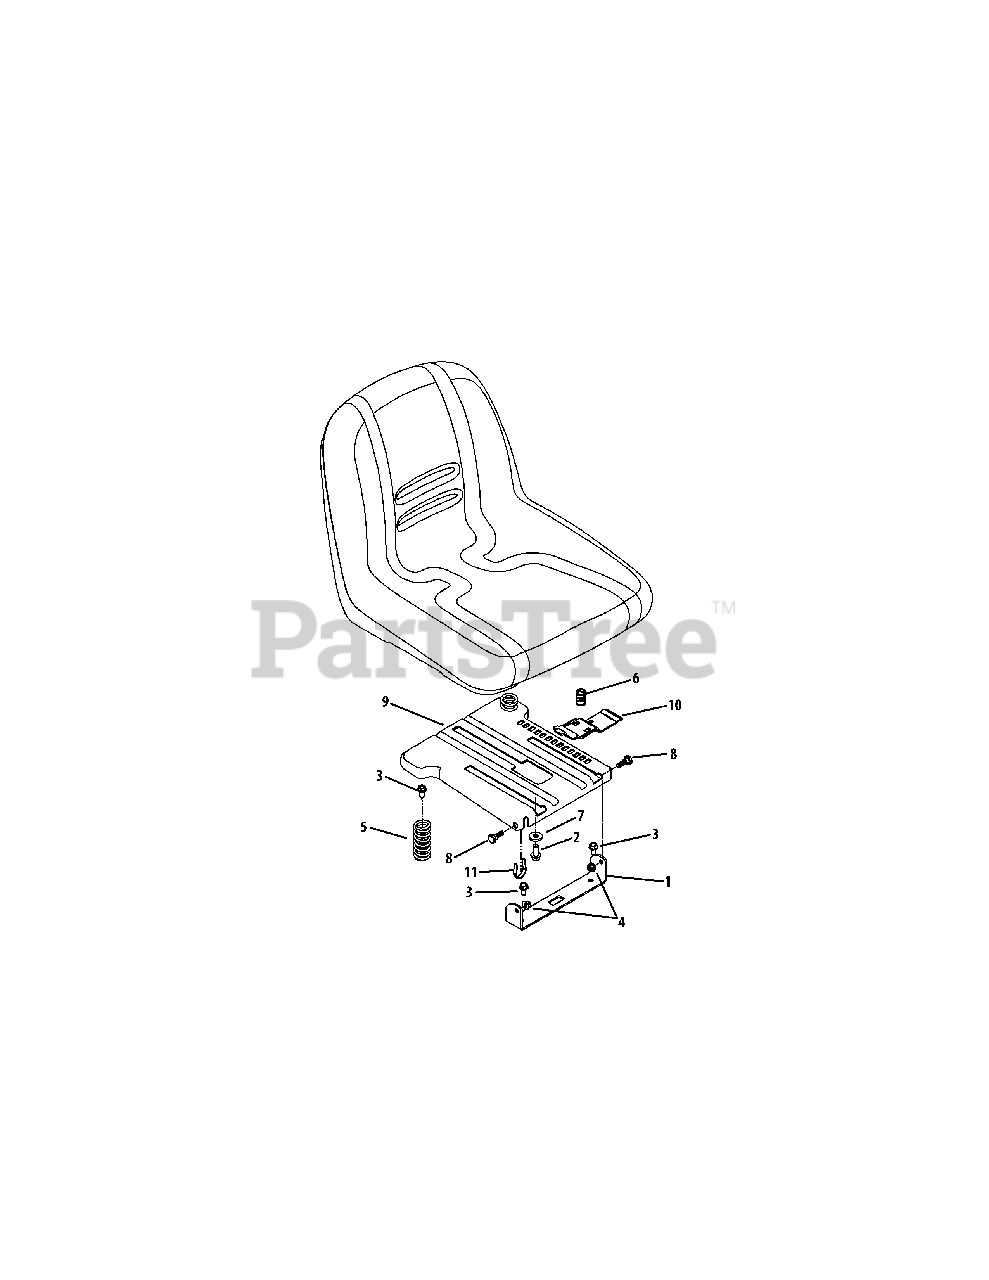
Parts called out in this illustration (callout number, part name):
1	Seat Bracket
2	Hex Flange Bolt, 3/8-16 x .875
3	Hex Washer Screw, 5/16-18 x .750
4	Flange Lock Nut, 5/16-18
5	Compression Spring
6	Compression Spring
7	Flat Washer, .385 x 1.0 x .135
8	Shoulder Screw, .437 x .268 x 5/16-18
9	Seat Mount Bracket
10	Seat Adjustment Lever
